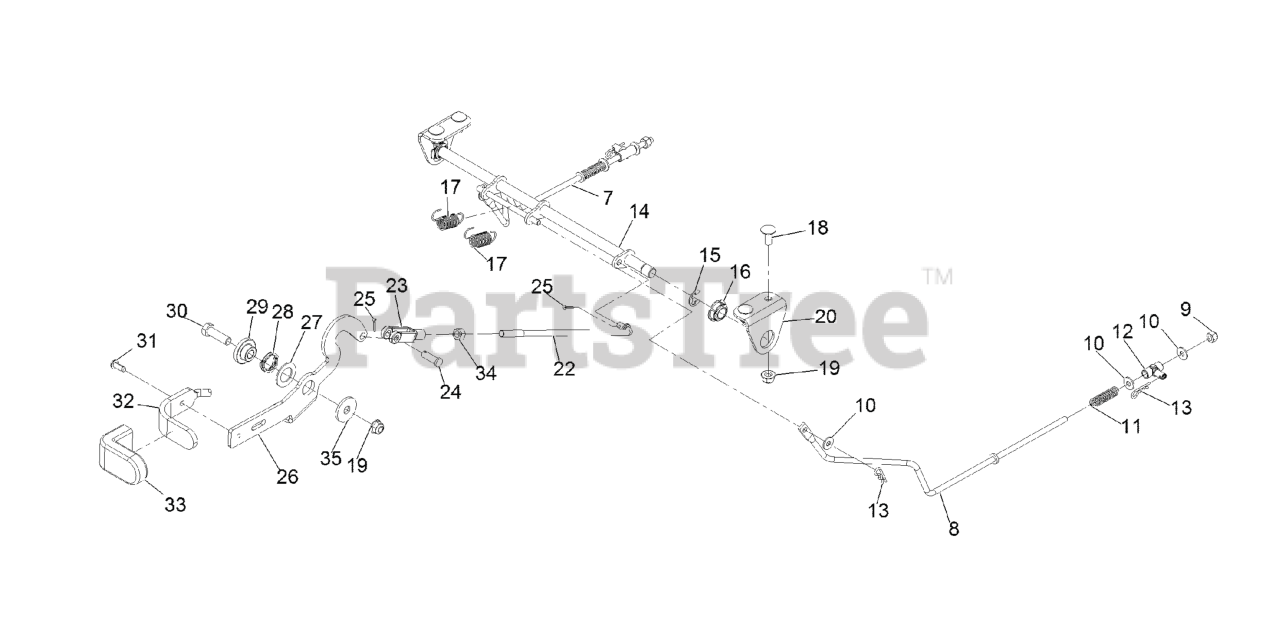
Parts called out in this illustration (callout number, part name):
7	ROD-BRAKE, RH
8	ROD-BRAKE, LH
9	NUT-LOCK, NI
11	SPRING-COMPRESSION
12	MOUNT-PIVOT
14	PIVOT-BRAKE
15	RING-RETAINING, EXTERNAL
16	BEARING-SPHERICAL
17	SPRING-EXTENSION
18	SCREW-CARR
19	NUT-HF, NI
20	ANGLE-MOUNT PIVOT
22	ROD-LINK HANDLE
23	YOKE-ADJUSTABLE
24	PIN-CLEVIS
25	PIN-COTTER
26	LEVER-BRAKE
27	WASHER-THRUST
28	WASHER-WAVE
29	PIVOT-FLANGE
30	SCREW-HH
32	HANDLE-BRAKE
33	GRIP-LEVER
34	NUT-HEX
35	WASHER
